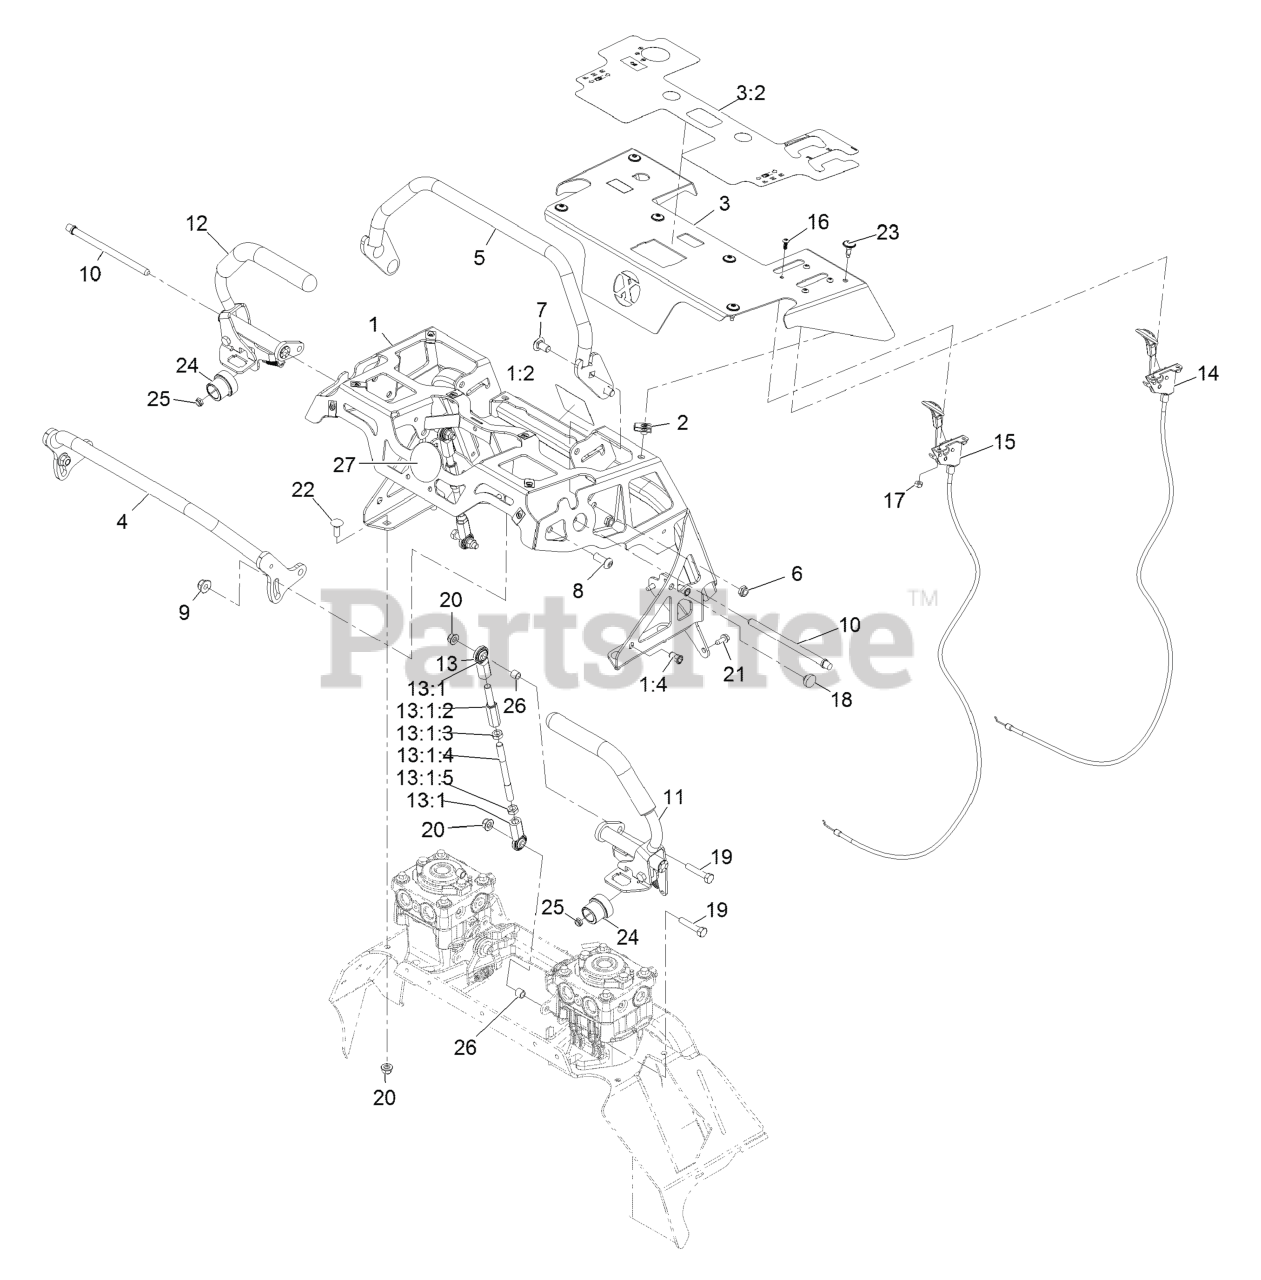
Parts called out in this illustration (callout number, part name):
1	ASM-CTRL TOWER
1:2	DECAL-HYD FLUID WARN
1:4	NUT-CLINCH,HEX
3	ASM, CONTROL PANEL W/ DECALS
3:2	DECAL-CONTROL PANEL NON-EFI
4	WELD, FRONT REF BAR
5	WELD, REAR REF BAR
7	SCREW-CARR
8	SCREW-HSBH
9	NUT-HF, NI
10	PIN, PIVOT
11	ASM, MOTION CONTROL, LT
12	ASM, MOTION CONTROL, RT
13	ASM, LINKAGE
13:1	ASM, Motion Control Link
13:1:2	ROD-ADJUSTMENT
13:1:3	NUT-HEX JAM, LH
13:1:5	NUT-HJ
14	CONTROL, CHOKE
15	CONTROL, THROTTLE
16	SCREW, BHCS
17	NUT-LOCK, NI
19	SCREW-HH
20	NUT-HF, NI
21	SCREW-HWH
22	SCREW-CARR
23	SCREW, TORX
25	NUT-LOCK, NI
27	DECAL-COVER
